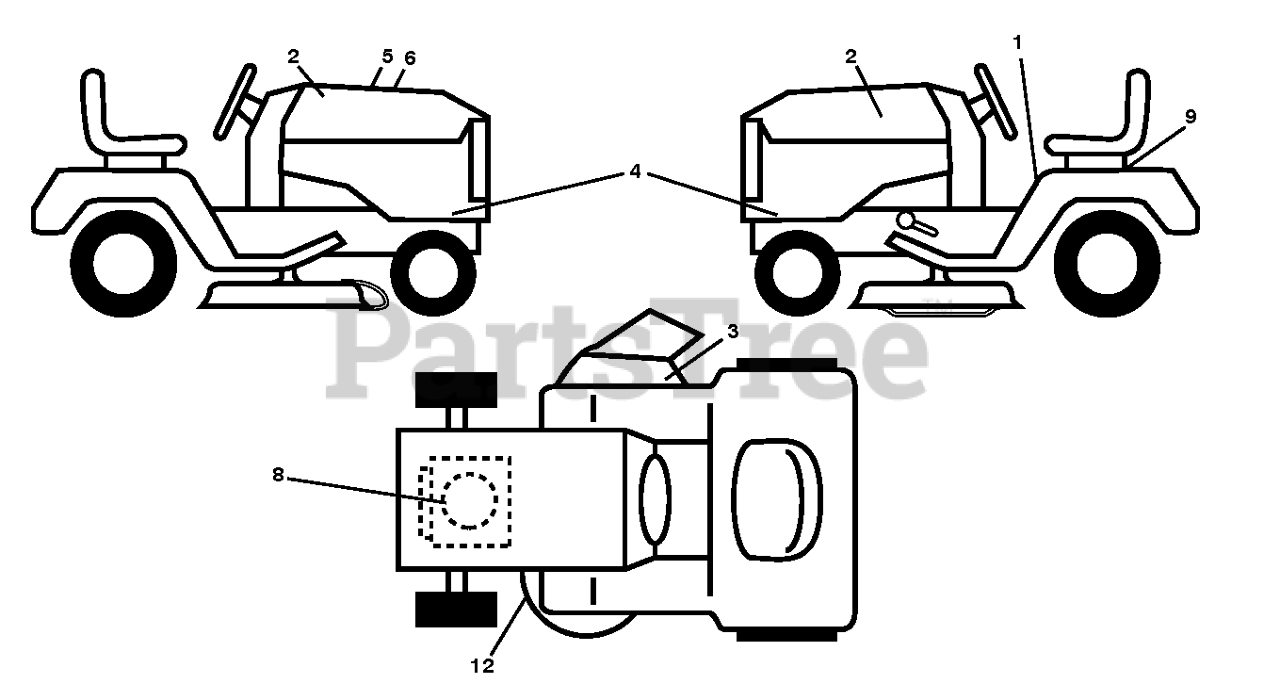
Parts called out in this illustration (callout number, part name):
1	DECAL.FENDER.WARNING
2	RP.DECAL.BADGE.170MM.TEXTLOGO
3	DECAL.WARN.KEEP.HAND.AWAY
4	DECAL.SDPNL.HUSGT2.YTH2042.
5	DECAL.WARNING.CUST.RESP.E85.
6	DECAL RPL.BSM33.INT.TLW.42.K46
8	DECAL.ENG.BS.20HPXRD.SL.278416
9	DECAL BTRY SYMBOLS
12	DECAL V BELT SCHEMATIC
